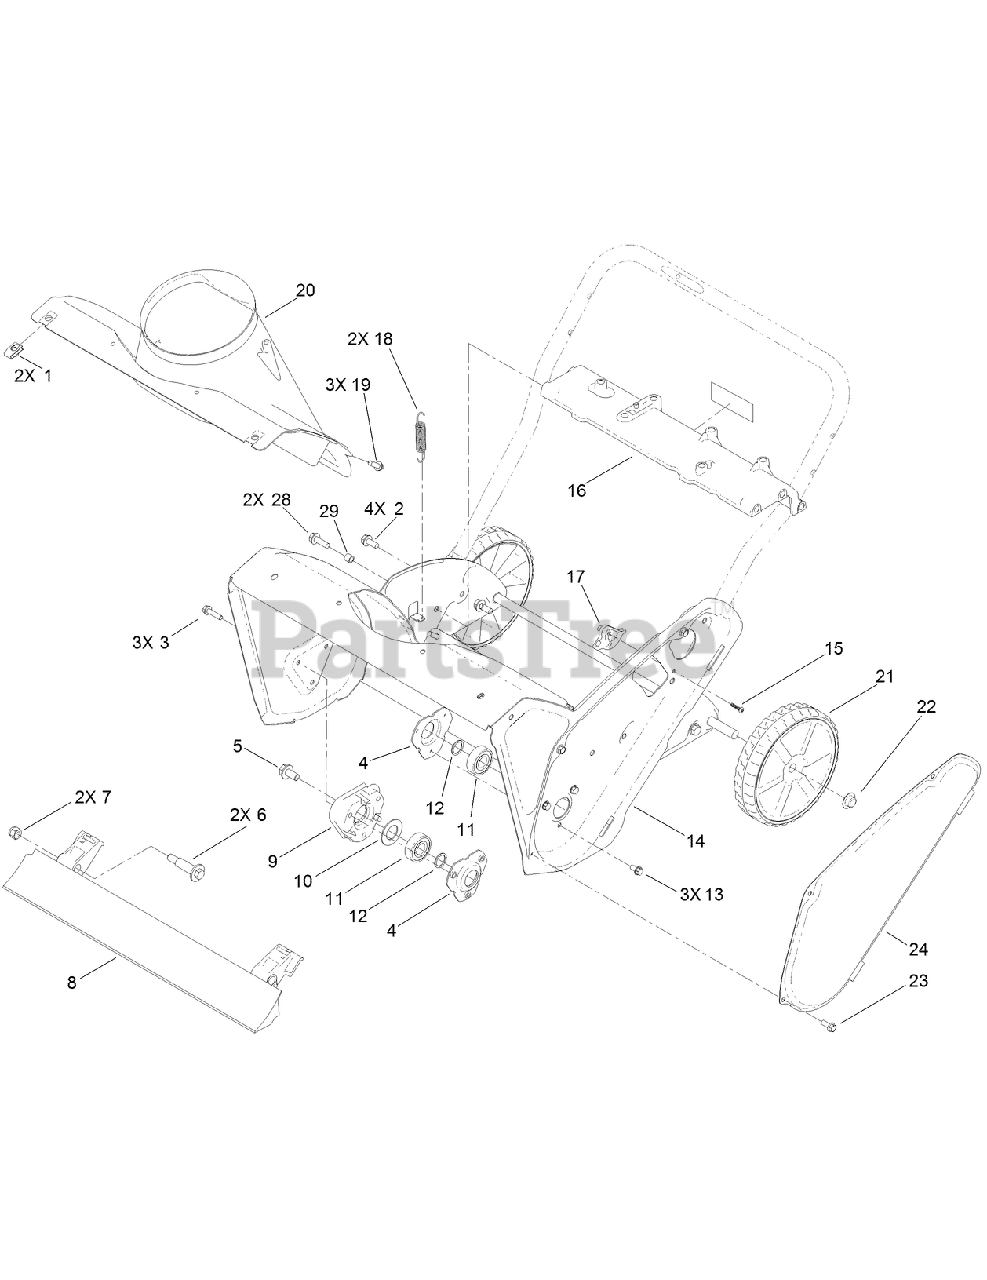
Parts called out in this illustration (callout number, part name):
2	SCREW-THD ROLL, HWH
3	SCREW-HWHTF
5	SCREW-HWH
7	NUT-LOCK, NI
9	SPACER-BEARING, RH
10	WASHER-RUBBER
12	WASHER-THRUST
13	SCREW-HWH
14	HOUSING-AUGER
15	SCREW-PPH
16	BRACE-FRAME
17	GUIDE-CABLE, CLUTCH
18	SPRING-EXTENSION
19	SCREW-HWH
20	CHUTE-LOWER
21	WHEEL ASM
22	NUT-PUSH
23	SCREW-HWH
24	COVER-BELT
28	SPACER
29	SCREW-HWHTF
